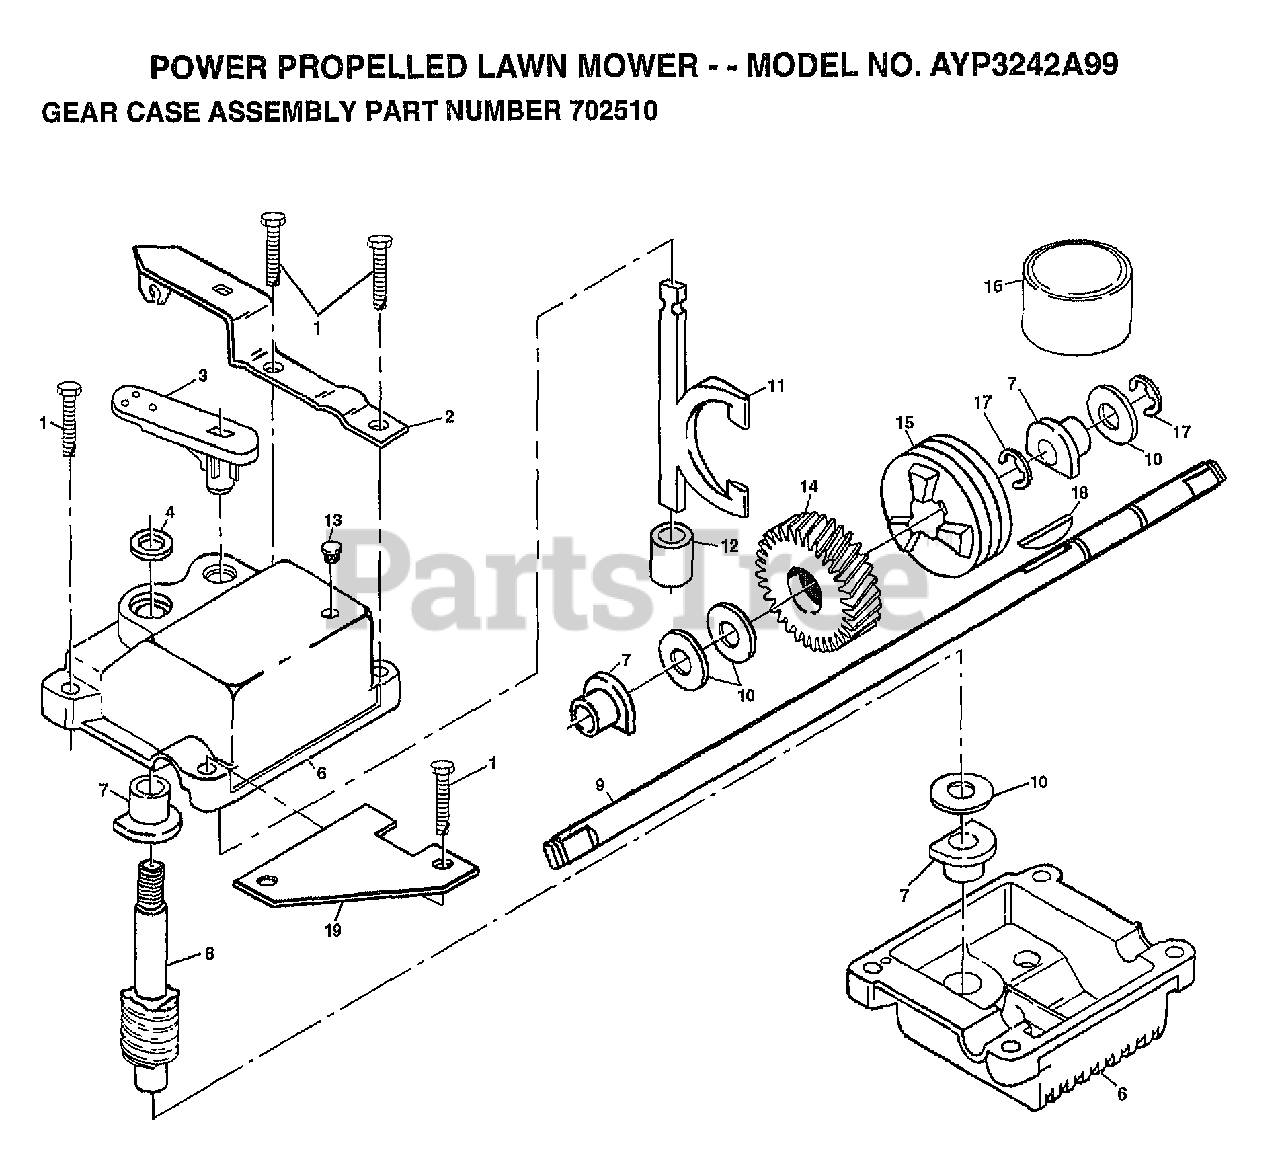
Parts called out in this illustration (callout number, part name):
1	SCREW.1/4-20
2	BRACKET.GEARCASE
3	SHIFTER
4	SEAL
6	KIT GEARCASE HALV
7	BEARING
8	SHAFT.WORM
9	SHAFT.DRIVE.SD
10	THRUST WASHER
11	CLUTCH YOKE
12	BUSHING.GEAR BOX
13	PLUG PM
14	GEAR.HELICAL
15	CLUTCH JAW
17	RING T
18	HI PRO KEY
